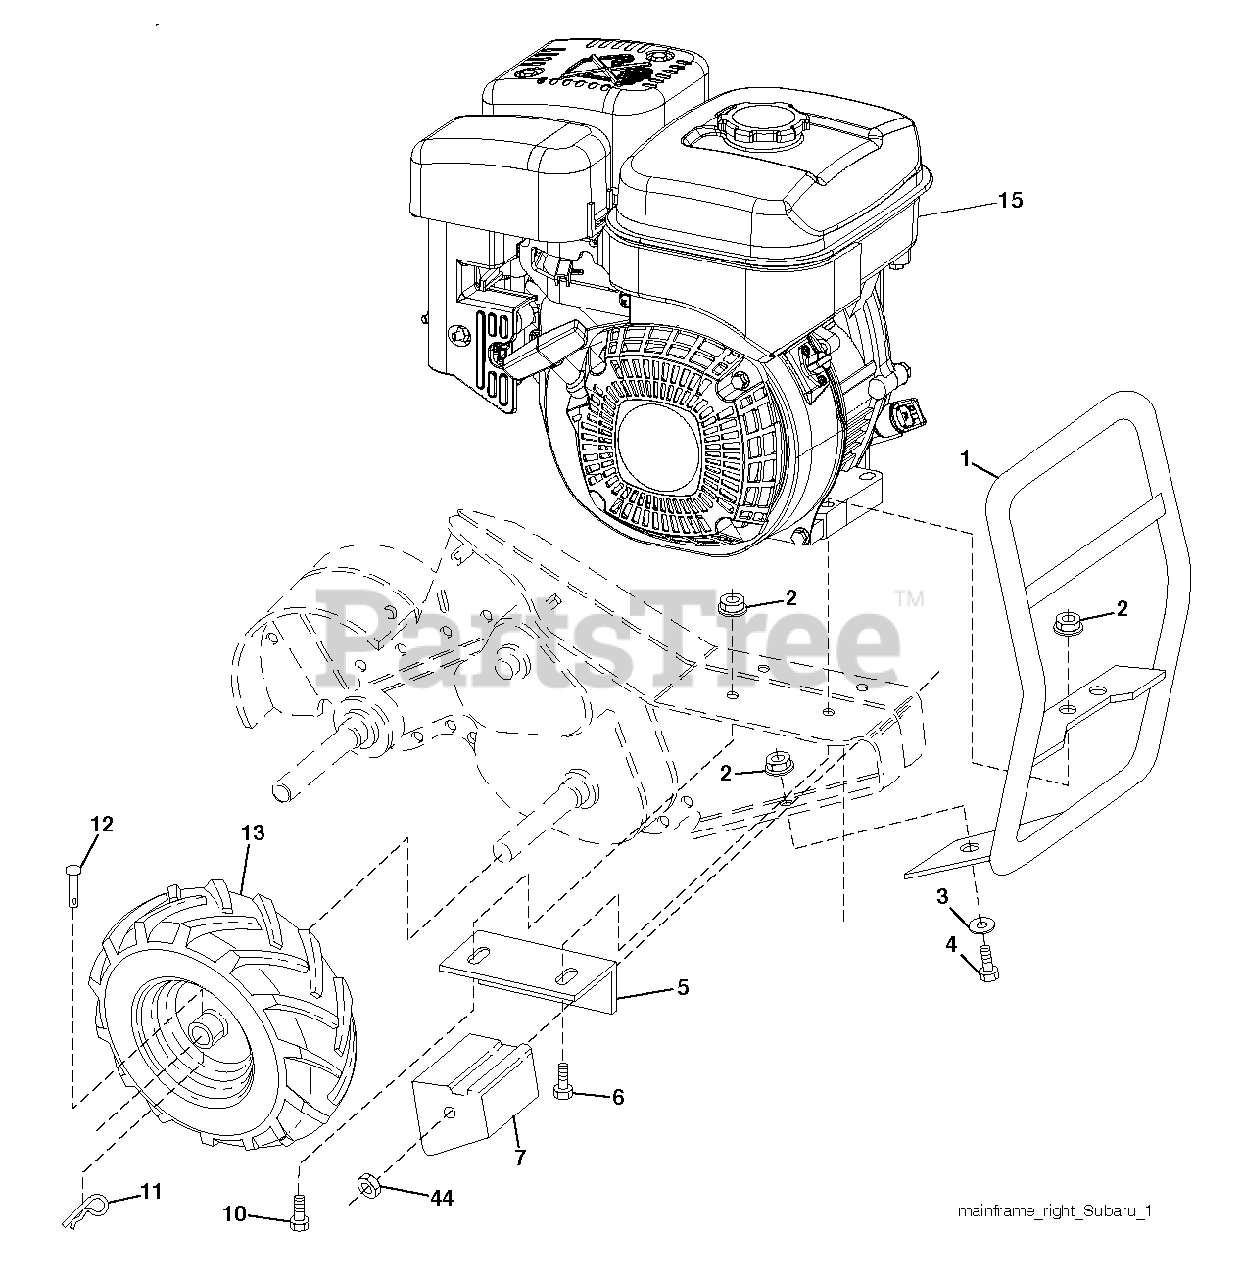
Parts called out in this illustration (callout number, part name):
1	BUMPER.ASM.TILLER.BLACK
2	LOCKNUT-FLANGE 5/16-18
3	WASHER
4	BOLT
5	BRACKET.REINFORCEMENT.RH.BLACK
6	BOLT, HEX 5/16-18X1-3/4
7	COUNTERWEIGHT.RH
10	BOLT
11	RETAINER M
12	RIVET
13	WHEEL.ASM.DRT.13X5-6.RT.SILVER
